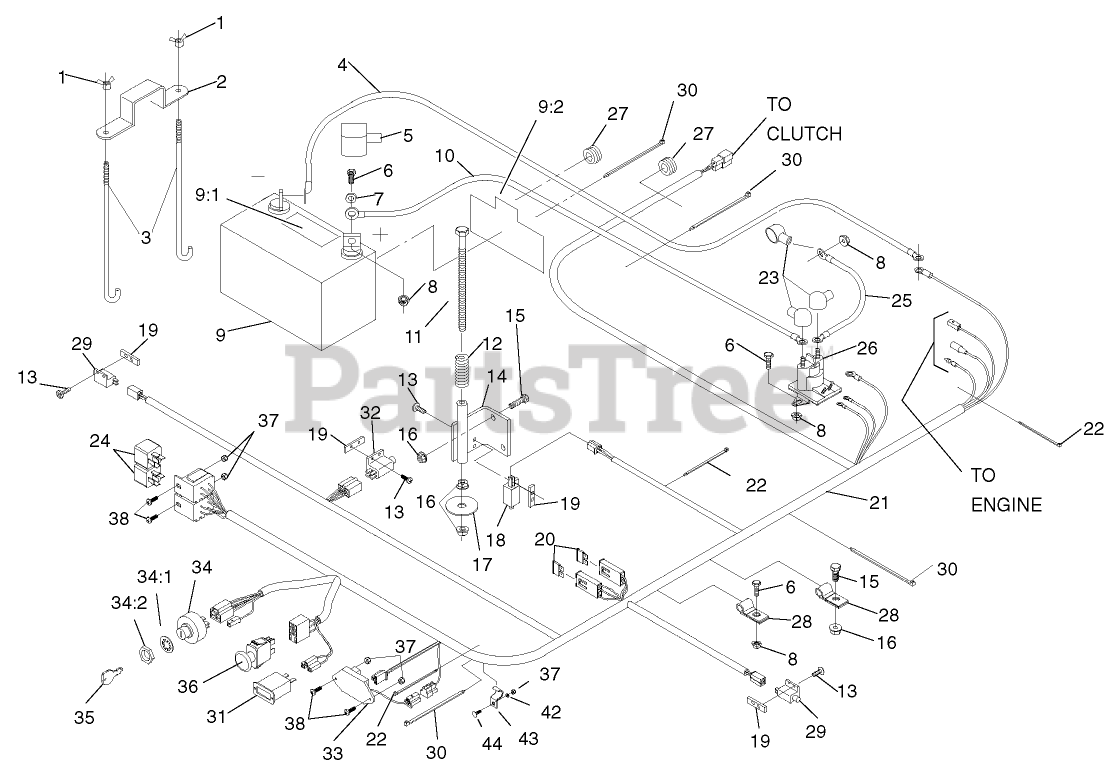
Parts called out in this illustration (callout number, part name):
1	WINGNUT
2	STRAP-HOLDDOWN
3	BOLT-HOLDDOWN
4	CABLE-GROUND, NEGATIVE
5	INSULATOR-BATTERY
6	SCREW-HH
7	WASHER-FLAT
8	NUT-HF
9	BATTERY
9:1	Decal-Battery
9:2	Decal-Battery
10	CABLE-BATTERY, POSITIVE
11	SCREW-HH
12	SPRING-SWITCH, SEAT
13	SCREW-PPH
14	BRACKET-SWITCH, SEAT
15	SCREW-HH
16	NUT-HF
17	WASHER
18	SWITCH-CLOSED, NORMALLY
19	PLATE-TAPPED
20	FUSE-BLADE TYPE, 20 AMP
21	HARNESS-WIRE
22	TIE-CABLE
23	INSULATOR-SOLENOID
25	CABLE-STARTER, POSITIVE
26	SWITCH-SOLENOID
27	GROMMET
28	CLIP-LOOM
29	SWITCH-OPEN, NORMALLY
30	TIE-PLASTIC
31	METER-HOUR
32	SWITCH
33	MODULE-DELAY, SEAT
34	Key Switch ASM
34:1	WASHER-TOOTH, INTERNAL
34:2	NUT-HH
35	KEY-IGNITION
36	SWITCH-DELTA
37	NUT-LOCK, NI
38	BOLT-CARR
42	WASHER-FLAT
43	CLIP-HALF, LOOM
44	BOLT-CARR
